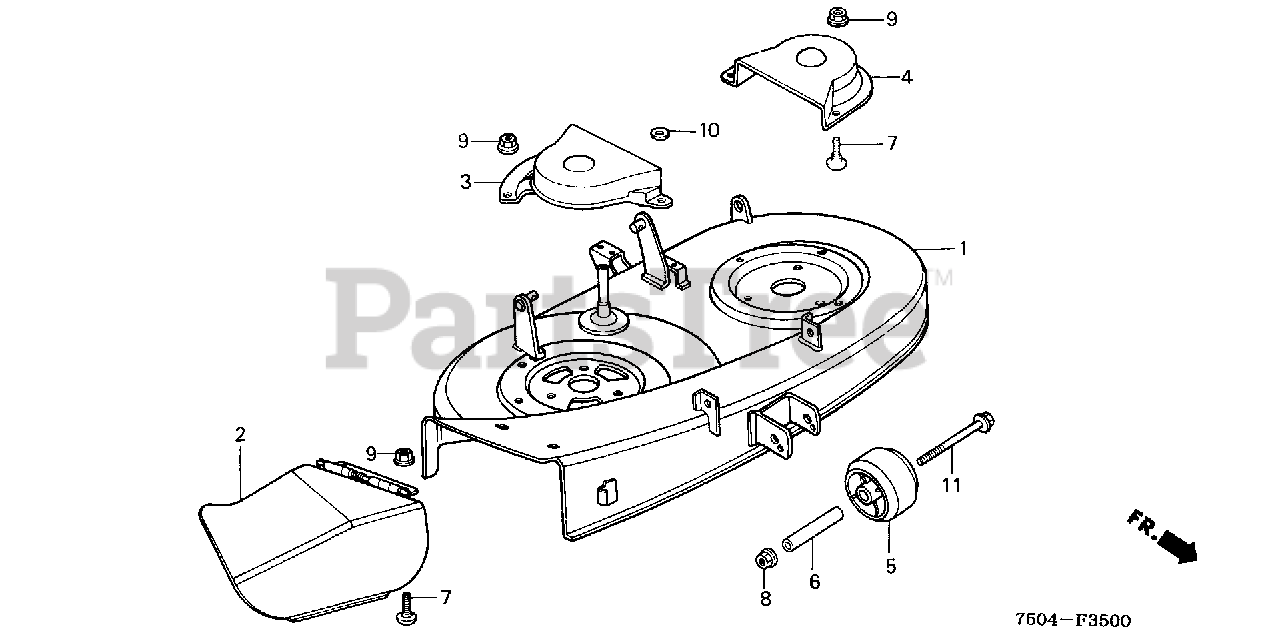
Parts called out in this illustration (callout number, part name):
1	HOUSING, CUTTER
2	ADAPTER, DISCHARGE
3	COVER, R. BELT
4	COVER, L. BELT *NH35M* (CLOUD SILVER METALLIC)
5	ROLLER, ANTI-SCALP
6	COLLAR, ANTI-SCALP ROLLER
7	BOLT, SPECIAL (9X15)
8	NUT, U (10MM)
9	NUT, FLANGE (8MM)
10	WASHER, PLAIN (8MM)
11	BOLT, FLANGE (10X110)
